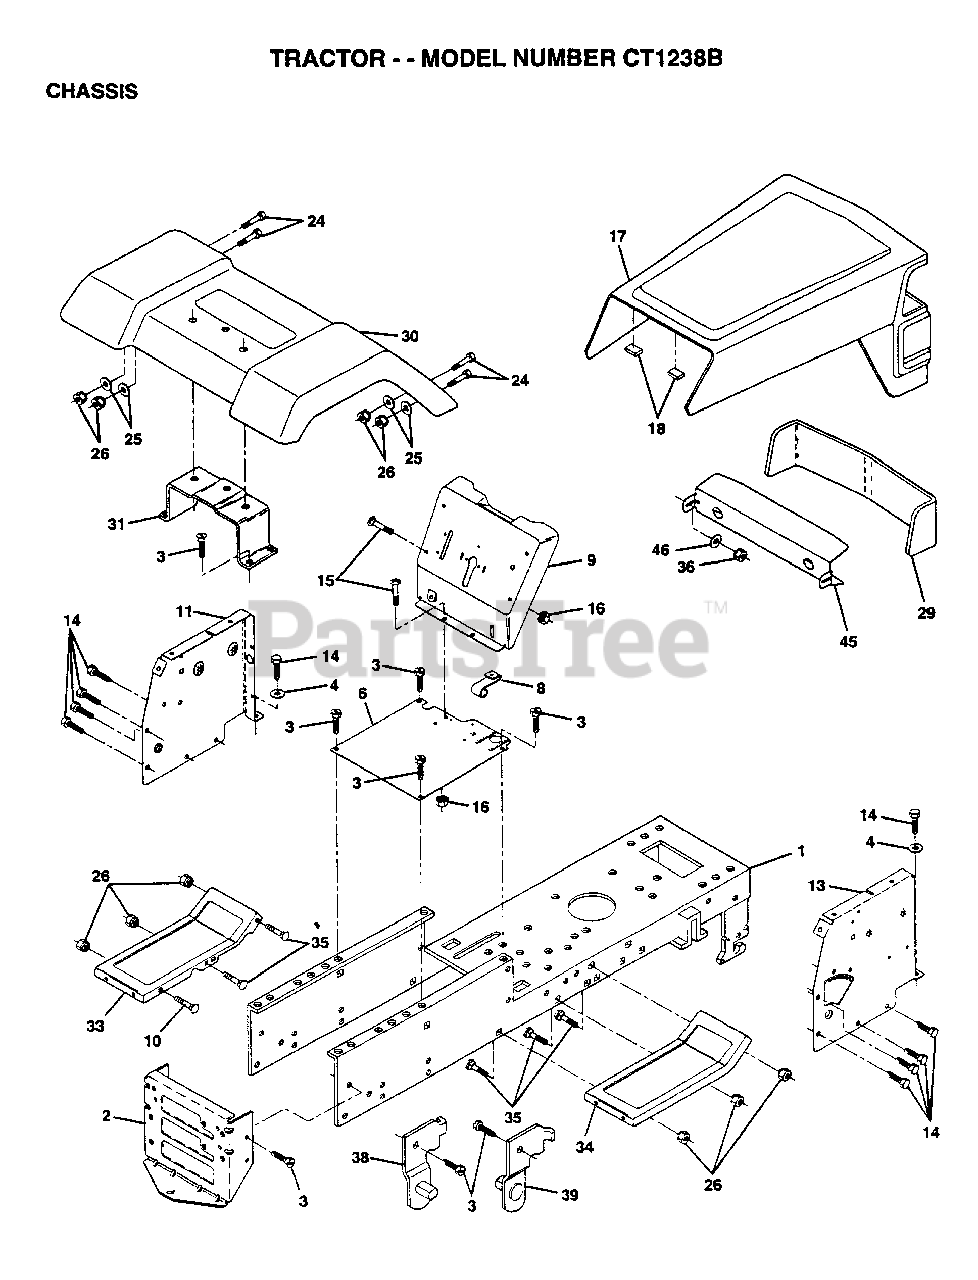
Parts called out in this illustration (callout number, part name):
1	CHASSIS.WLD.11GA
3	SCREW
4	WASHER
8	"CLIP,INSULATOR"
9	DASH SILKSCRN 1
11	DASH PANEL LH
14	SCREW LT
15	SCREW
17	HOOD/GRILL ASM
24	BOLT
25	WASHER
26	NUT
29	LENS SERVICE KIT
30	FENDER
31	BRKT FENDER
33	FOOTREST LH
34	FOOTREST RH
35	BOLT
36	PAL NUT LT
38	BRACKET ASM LH
39	BRACKET ASM RH
46	RETAINER
